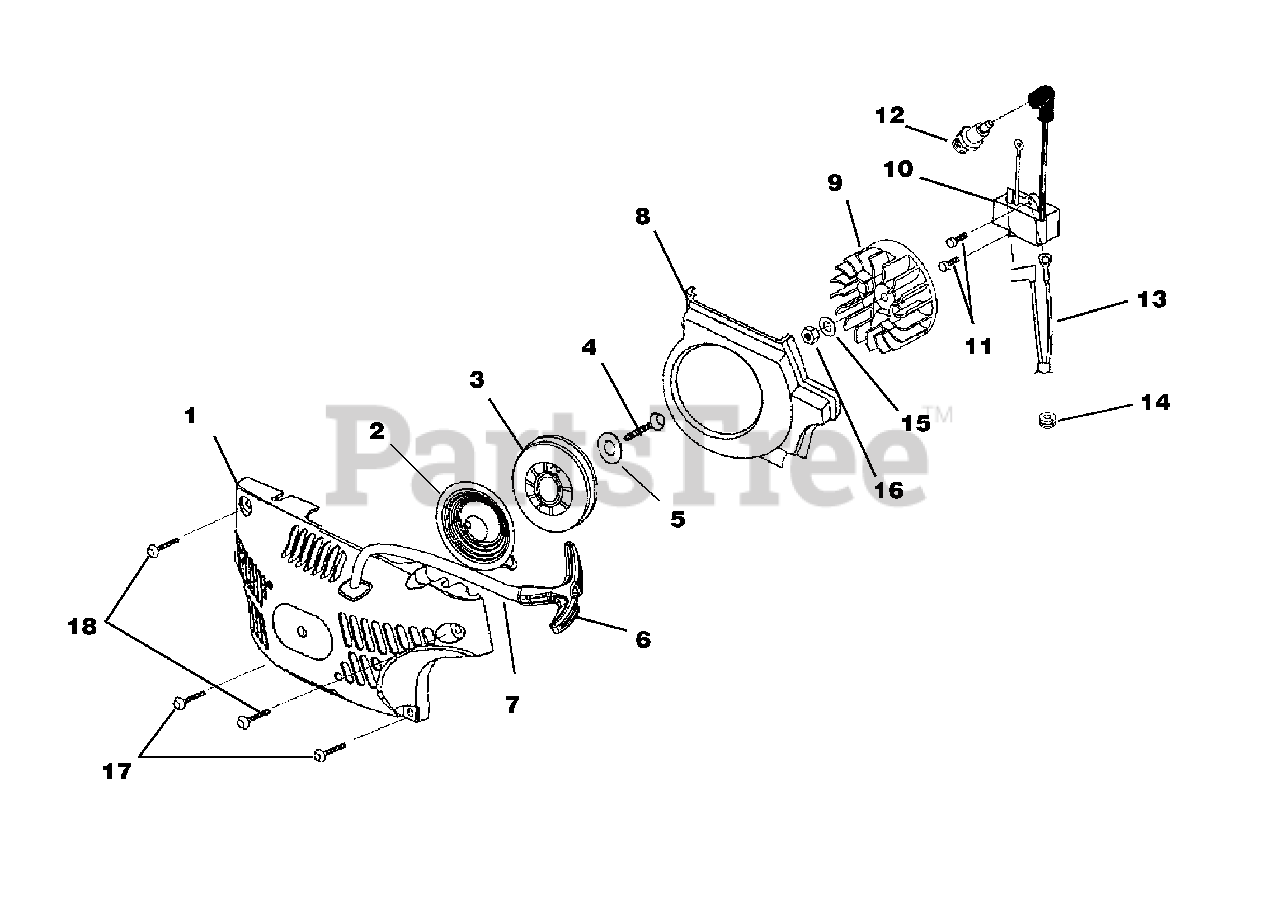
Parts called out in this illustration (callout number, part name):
1	Starter Kit
2	Spring & Container
3	Pulley, Starter
4	Screw, Thread Form (10-14 x 5/8")
5	Washer, Retaining
6	Grip, Starter
7	Rope, Starter 46"
8	Baffle, Fan Housing
9	Rotor & Starter Pawl
10	Ignition Kit
11	Screw, Thread Form (8-32 x 5/8")
12	Spark Plug
13	Ignition Switch Harness
14	Grommet, Wire Harness (Split)
15	Washer, Flat
16	Nut, Jam
17	Screw, Truss Hd. (10-14 x 7/8")
18	Screw, Truss Hd. (10-14 x 5/8")
